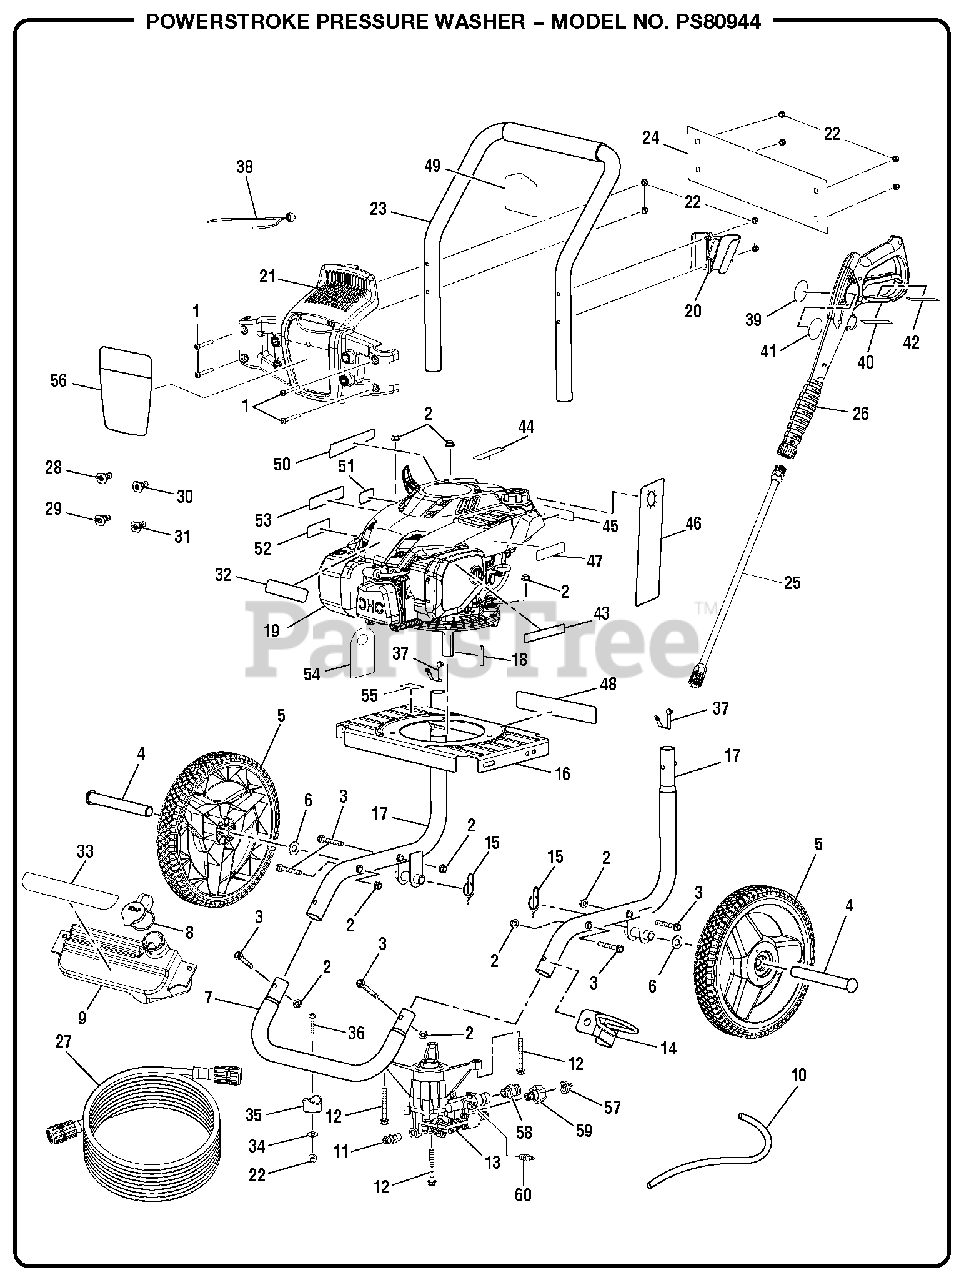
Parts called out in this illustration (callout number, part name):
1	Screw (1/4-20 x 2.27 in., T30 Torx Hd.)
2	Flange Nut (M8 x 1.25)
3	Bolt (M8 x 55 mm)
6	Washer (1/2 in.)
7	Front Frame Assembly
8	Soap Tank Cap
9	Soap Tank
10	Chemical Siphon Tube
11	Thermal Release Valve
12	Bolt (M8 x 60 mm, Flange Hd.)
13	Pump
14	Wand Holder Loop
15	Ring Clip
16	Engine Plate
17	Main Frame Assembly
18	Output Shaft Key (35 mm)
20	Wand Holder
21	Hose and Nozzle Assembly
22	Lock Nut (1/4-20)
23	Handle w/Foam
24	Quick Start Panel
25	Spray Wand
26	Trigger Handle Assembly
27	Hose (25 ft.)
28	Soap Nozzle
29	25deg Nozzle
30	40deg Nozzle
31	0deg Nozzle
32	Subaru Label
33	Detergent Tank Label
34	Washer (1/4 in.)
36	Screw (1/4-20 x 1.85 in., T30 Torx Hd.)
37	Spring Clip
38	Bungee Cord Assembly
39	Label (Wand Logo)
40	Fr/Sp Label (Wand Warning)
41	Label (Wand Warning)
42	Label (Wand Rating)
43	Inquiries Label
44	E85 Label
45	Do Not Mix Label
46	Warning Hangtag
47	Engine Start Label
48	Data Label
49	Nozzle Hangtag
50	Release Water Label
51	Lubricant Label
52	Hot Surface Label
53	Combustion Label
54	Oil Cap Hangtag
55	Oil Fill Location Label
56	Performance Label
57	Filter Screen
58	Outlet Tube
59	Inlet Tube
60	Detergent Suction Kit
